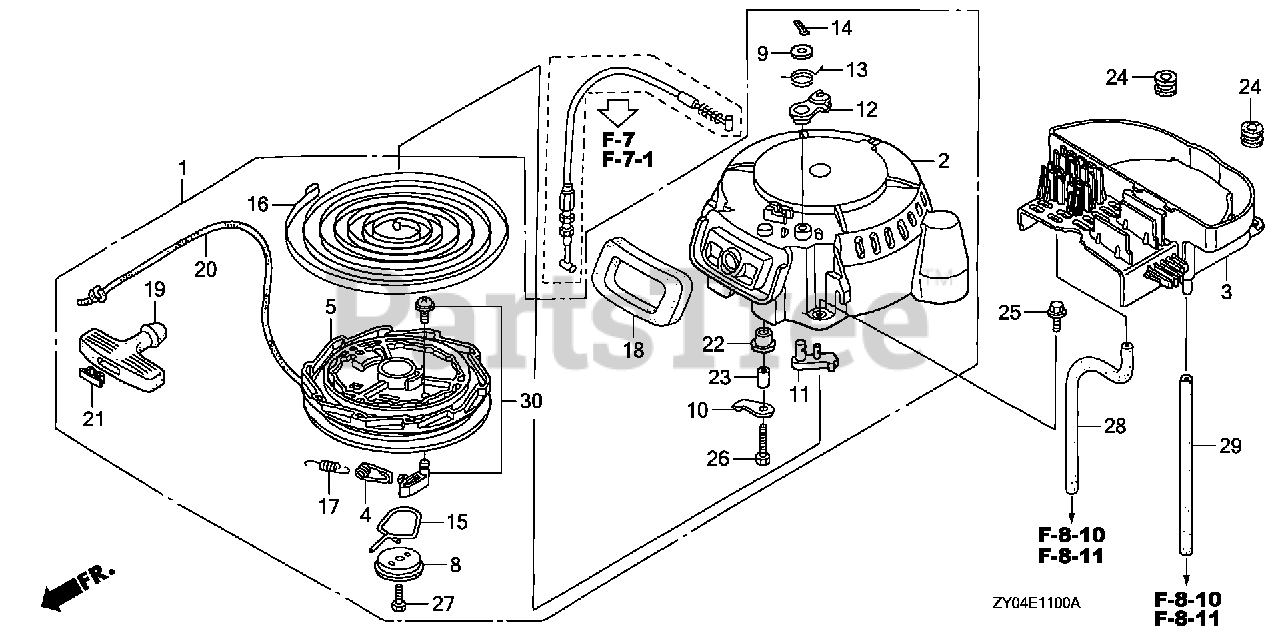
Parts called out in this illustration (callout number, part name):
1	STARTER ASSY., RECOIL
2	CASE, RECOIL STARTER
3	CASE B, STARTER
4	GUIDE, RECOIL STARTER
5	REEL, RECOIL STARTER
6	RATCHET SET, STARTER
6	RATCHET, STARTER
7	RATCHET SET, STARTER
7	E-RING
8	PLATE, FRICTION
10	WASHER, THRUST
11	STOPPER, REEL
12	ARM, STOPPER
13	SPRING, STOPPER
14	PIN, SPLIT
15	SPRING, FRICTION
16	SPRING, RECOIL STARTER
17	SPRING, RETURN
18	SEAL, RECOIL
19	GRIP, STARTER
20	ROPE, RECOIL STARTER (N/A: USE P/N 08550-ZG921-11)
21	CAP, STARTER KNOB
22	ROLLER, STARTER
23	GUIDE, ROLLER
24	GROMMET, ENGINE COVER
25	BOLT, FLANGE (6X22)
26	BOLT, HEX. (6X25)
27	BOLT, HEX. (6X14)
28	TUBE, WATER DRAIN
29	BULK HOSE, VACUUM (8X1000) (8X240)
30	RATCHET SET, STARTER
